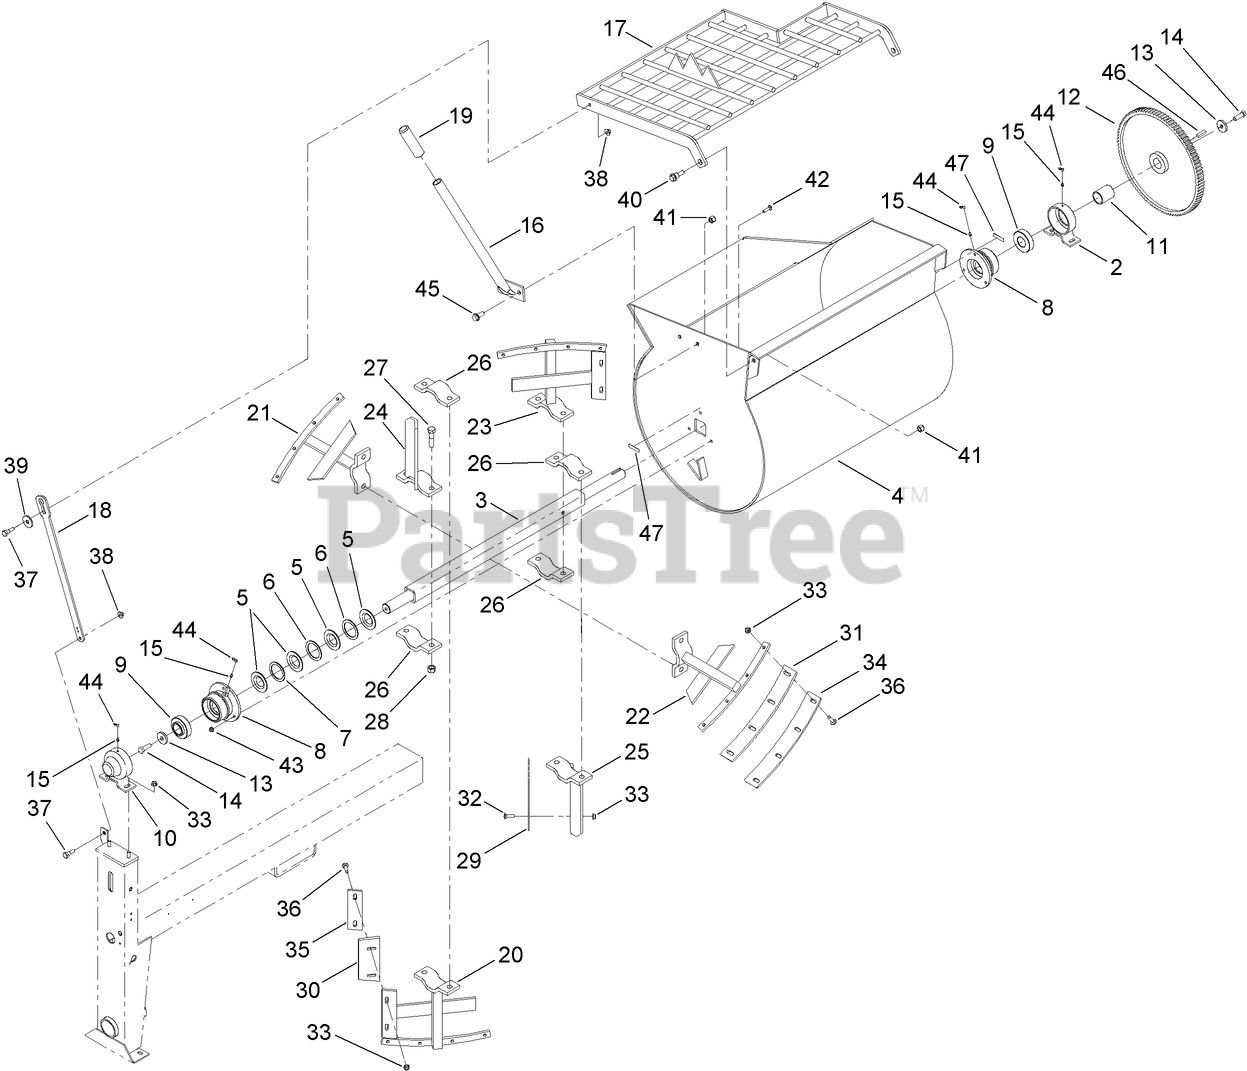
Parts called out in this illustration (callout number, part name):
2	TRUNNION
3	SHAFT-PADDLE
5	SEAL-DRUM
6	WASHER-FLAT
7	WASHER-SPLIT
8	HOUSING-BEARING
9	BEARING-BALL
10	TRUNNION-CAPPED
11	SPACER-SHAFT, DRUM
12	GEAR-94 TEETH
13	WASHER-FLAT
14	SCREW-HH
15	FITTING-GREASE
16	HANDLE-DUMP
17	GUARD-DRUM
18	GUARD-LIFTER
19	GRIP-HAND
20	PADDLE-FRONT
21	PADDLE-MID
22	PADDLE-MID
23	PADDLE-REAR
24	PADDLE-PUSHER
25	PADDLE-PUSHER
26	CLAMP-PADDLE
27	SCREW-HH
28	NUT-LOCK, NI
29	BAR-BACKER, PUSHER END
30	BLADE-RUBBER, MIXER END
31	BLADE-RUBBER, MIXER TOP
32	BOLT-CARR
33	NUT-HF, NI
34	BAR-BACKER, TOP
35	BAR-BACKER, END
36	SCREW-CARR
37	BOLT-SHOULDER
38	NUT-FLANGE
39	Washer-Thrust
40	SCREW-SHOULDER, HHF
41	NUT-LOCK, NI
42	SCREW-CARR
43	NUT-HF, NI
44	CAP-PLUG
45	SCREW-HHF
46	KEY-SQUARE
47	DECAL-GREASE
